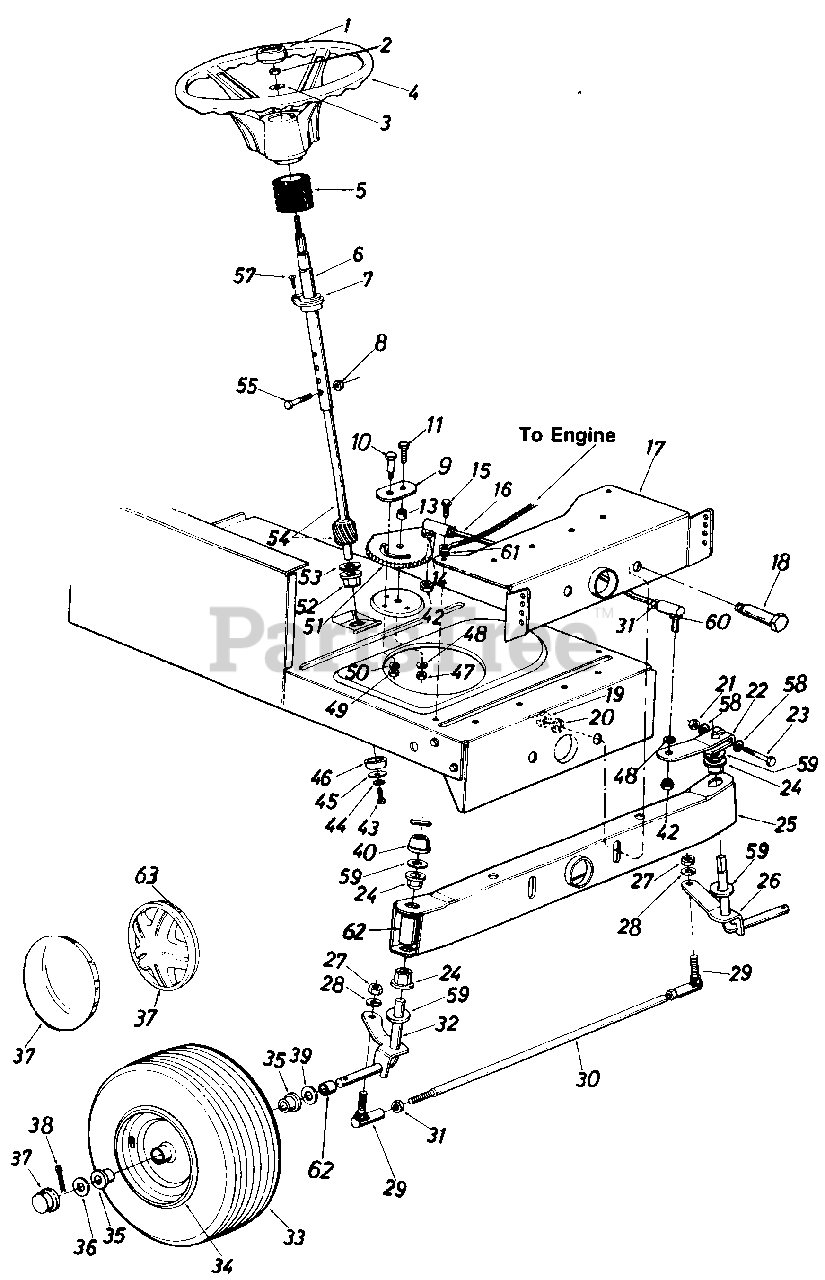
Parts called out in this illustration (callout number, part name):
1	Steering Wheel Cap
2	Hex L-Nut 5/16-24 Thd.
3	Belleville Wash. .345" I.D.
4	Steering Wheel
5	Steering Bellow
6	Steering Column Ass'y.
7	Flange Bearing .890 I.D. x 1.36 O.D.
8	Hex L-Nut 1/4-20 Thd.
9	Retainer Plate
10	Shoulder Bolt .437" Dia. x .35 Lg. 5/16-18 Thd.
11	Hex Bolt 3/8-24 x 1.0" Lg. (Grade 5)
13	Spacer .380" I.D. x.625" O.D. x .227
14	L-Wash. 3/8" I.D.
15	Hex Wash. Hd. Self-Tap Scr.
16	Steering Drag Link
17	Front Pivot Brkt.
18	Shoulder Bolt .498" Dia. x 2.04 Lg. 3/8-16 Thd.
19	Hex Nut 3/8-16 Thd.
20	L-Wash. 3/8" I.D.
21	Hex Cent. L-Nut 5/16-24 Thd.
22	Steering Arm Front Axle
23	Hex Bolt 5/16-24 x 2.00" Lg. (Grade 5)
24	Hex Flg. Brg. .634 I.D.
26	Front Axle Ass'y.-L.H.
27	Hex Nut 3/8-24 Thd.
28	L-Wash. 3/8" I.D.
29	Ball Joint 3/8-24 Thd.
30	Tie Rod
31	Hex Jam Nut 3/8-24 Thd.
32	Front Axle Ass'y.-R.H.
33	Wheel Ass'y. Comp.
34	Front Wheel Rim Only
35	Bearing
36	Fl-Wash. .635 I.D. x 1.59" O.D.
37	Front Wheel Hub Cap
38	Cotter Pin 1/8" Dia. x 1.25"
39	Fl-Wash. .640" I.D. x 1.24" O.D.
40	Push Cap 5/8" Dia. Rod
42	Hex Jam Nut 3/8-24 Thd.
43	Hex L-Bolt 5/16-18 x .62"
44	L-Wash. 5/16" I.D.*
45	Fl-Wash. .33" I.D. x 1.25" O.D.
46	Spacer (Plastic)
47	Hex Nut 3/8-24 Thd.
48	L-Wash. 3/8" I.D.
49	Hex Nut 5/16-18 Thd.
50	L-Wash. 5/16" I.D.
51	Steering Gear Segment
52	Hex Flg. Brg. .634 I.D.
53	Fl-Wash. (Hardened)
54	Steering Shaft Lower
55	Hex Bolt 1/4-20 x 1.25" Lg.
57	Oval Hd. Cr.-Sunk Scr. #10 x 5/8" Lg.
58	Wave-Wash. .32" I.D. x .62" O.D.
59	Fl-Wash. (Hardened)
60	Drag Link Ball Joint 3/8-24 Thd.
61	Ext. L-Wash. 5/16" I.D.
62	Plastic Tube
63	Spring Clip
